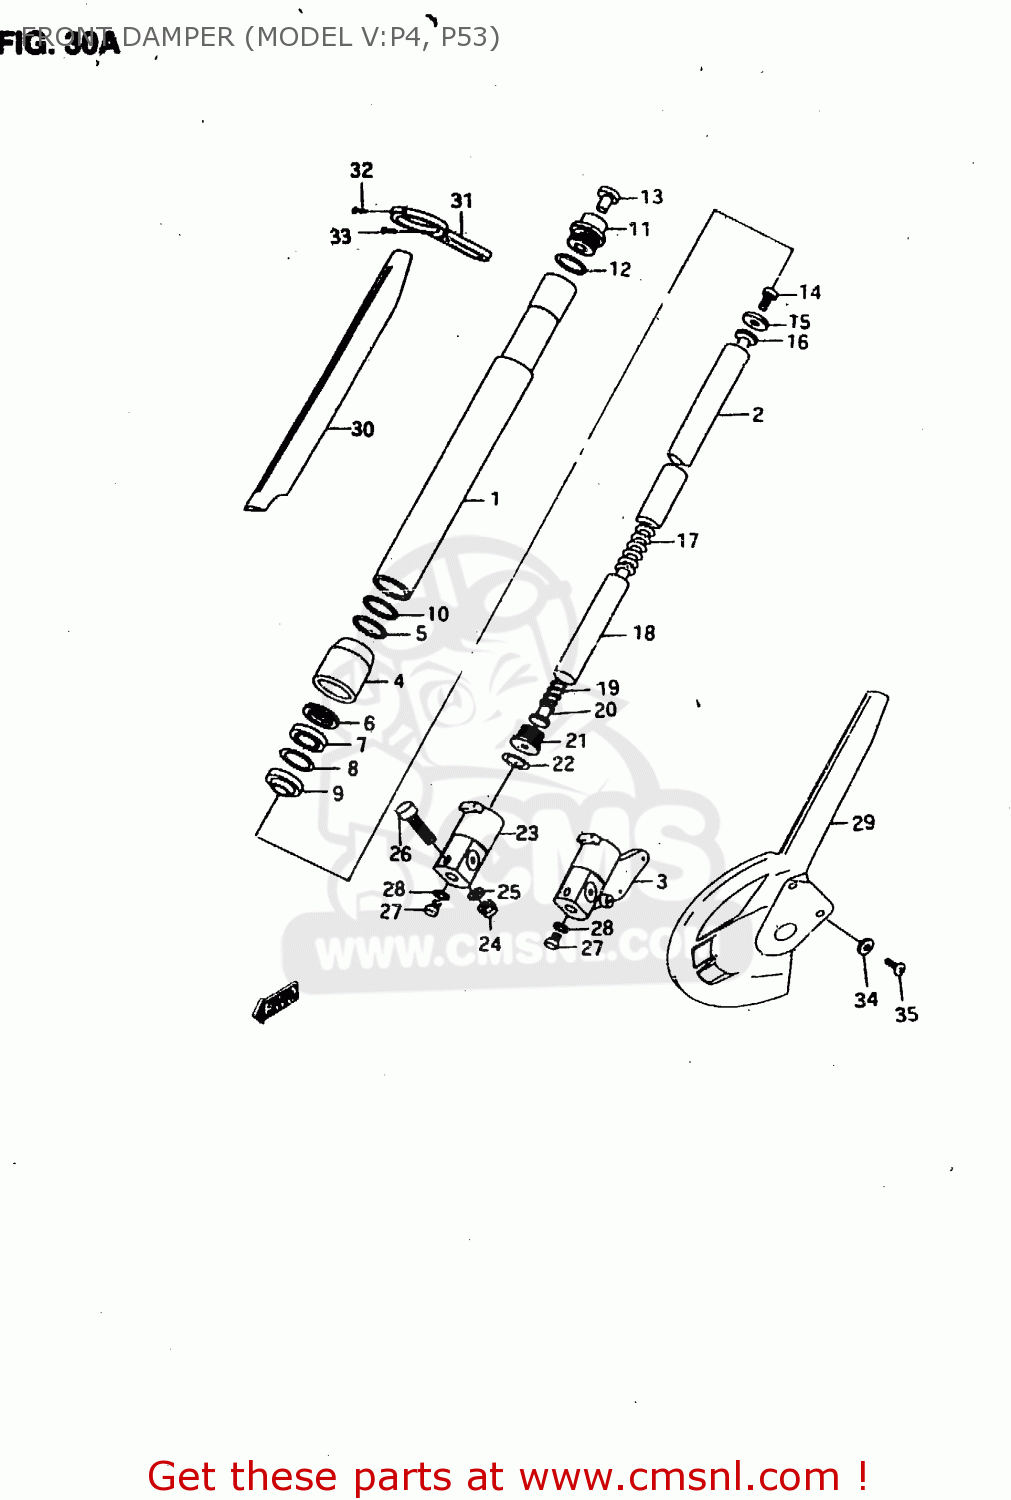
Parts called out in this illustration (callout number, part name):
1	TUBE, OUTER
2	TUBE, INNER
3	BRACKET, AXLE LH
4	CASE, SEAL
5	O RING
6	BUSH, GUIDE
7	OIL SEAL
8	O RING
9	PLATE
10	O RING
11	RING
12	O RING
13	CAP, FORK
14	BOLT
15	WASHER
16	GUIDE, SPRING
17	SPRING, MAIN
18	CYLINDER
19	SPRING, REBOUND
20	CYLINDER
21	BOLT
22	RING
23	BRACKET, AXLE RH
24	NUT
25	WASHER
26	BOLT
27	BOLT
28	GASKET (NAS)
29	PROTECTOR, LH
30	PROTECTOR, RH
31	GUIDE, HOSE
32	SCREW
33	SCREW
34	WASHER
35	SCREW
